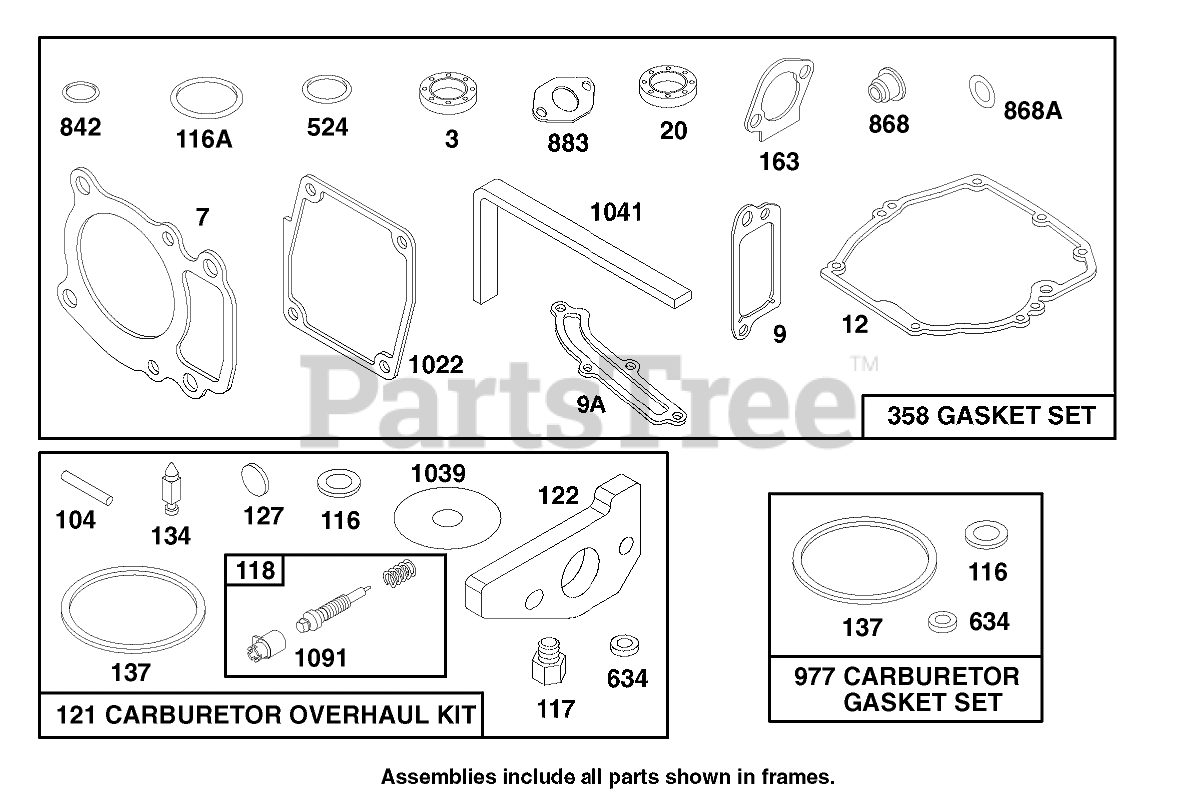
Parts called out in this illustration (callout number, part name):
3	SEAL - OIL
7	CYLINDER HEAD GASKET
9	BREATHER GASKET
9A	GASKET-BREATHER
12	ENGINE BASE GASKET
20	SEAL-OIL
104	FLOAT HINGE PIN
116	SEALING GASKET
116A	O RING SEAL
117	Jet-Main
118	VALVE/SPRING - NEEDLE
121	KIT-CARBURETOR OVERHAUL
122	ADAPTER ASSEMBLY
127	PLUG - WELCH
134	Valve-Inlet (Includes Seat)
137	FLOAT BOWL GASKET
163	AIR CLEANER GASKET
358	GASKET SET
524	O-RING
634	SEAL WASHER
842	O-RING
868	SealAssy-Valve
868A	Seal-Valve
883	EXHAUST GASKET
977	CARBURATOR GASKET SET
1022	ROCKER COVER GASKET
1039	FLOAT LIMITER
1041	SEAL - FOAM
1091	CAP - LIMITER
